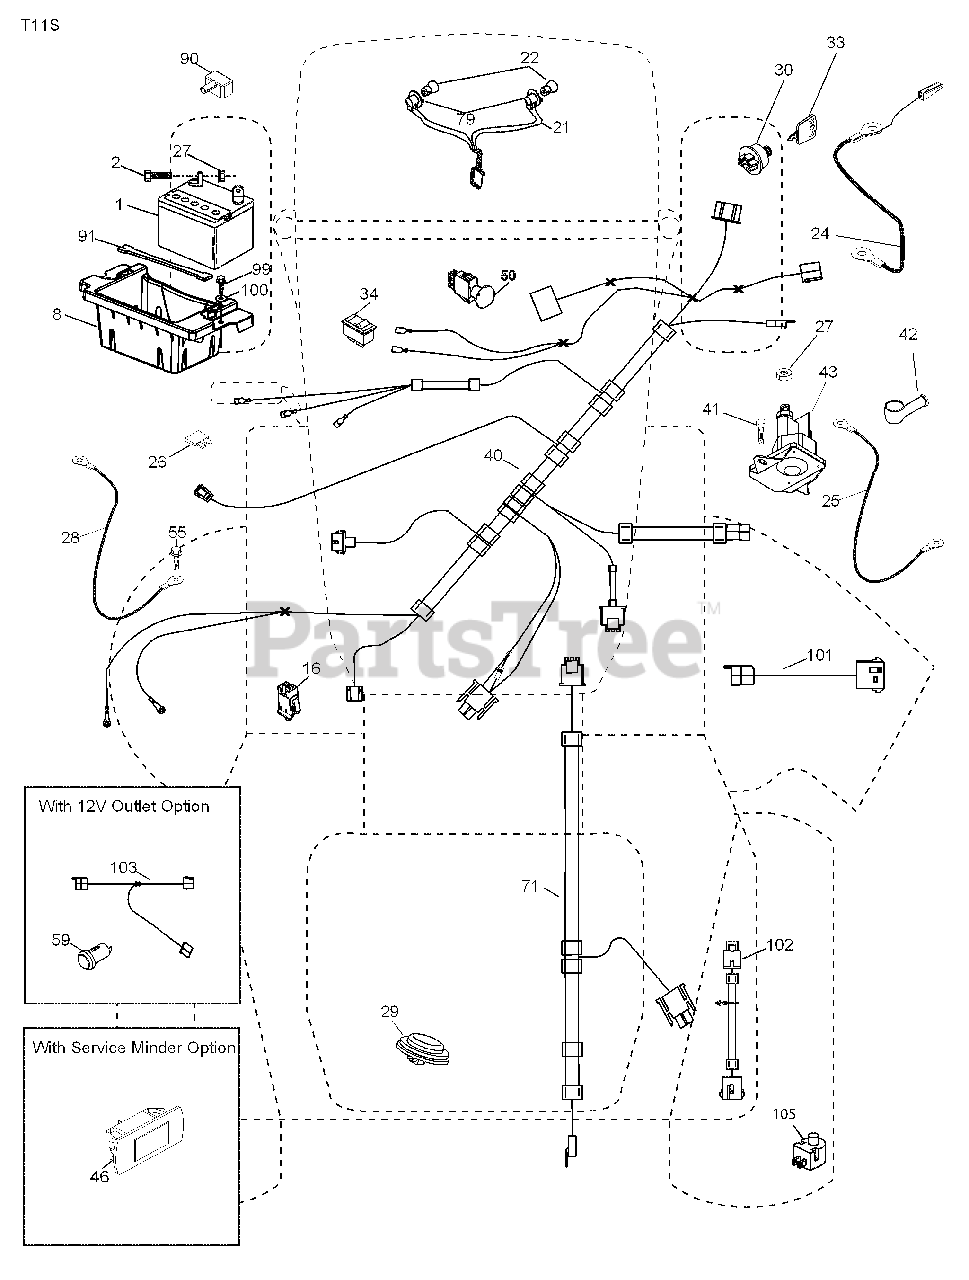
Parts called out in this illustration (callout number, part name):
1	Battery
2	Bolt Hex Hd 1/4-20 unc x 3/4
8	Battery Box
16	Switch Interlock
21	Harness Socket Light
22	Bulb, Light # 1156
24	Cable Battery
25	Cable Starter
27	Nut Keps Hex 1/4-20 unc
28	Cable Ground 21" Blk 6 Ga.
29	Switch Seat
30	Switch Ign
33	Key / Chain
34	Switch Light/Reset
40	Harness Ign. Dash
41	Screw Thd Cut 1/4-20 x 1/2
42	Cover Terminal Red
43	Solenoid
46	Gauge Hourmeter
50	Switch PTO
55	Screw Thdrol 5/16-18 x 3/4
59	Outlet 12-Volt
71	Harness Ign
79	Socket Asm Bulb Twistlock
90	Cover Terminal Battery
91	Strap Battery
99	Screw Hexwsh Thdrol 1/4-20 x 3/4
100	Washer 9/32 x 7/8 x 16 Ga.
101	Pigtail MATNLK
102	Harness Pigtail K46 Te x ROS
103	Harness Pigtail 12V Outlet
105	Switch Reverse TT Pedal
